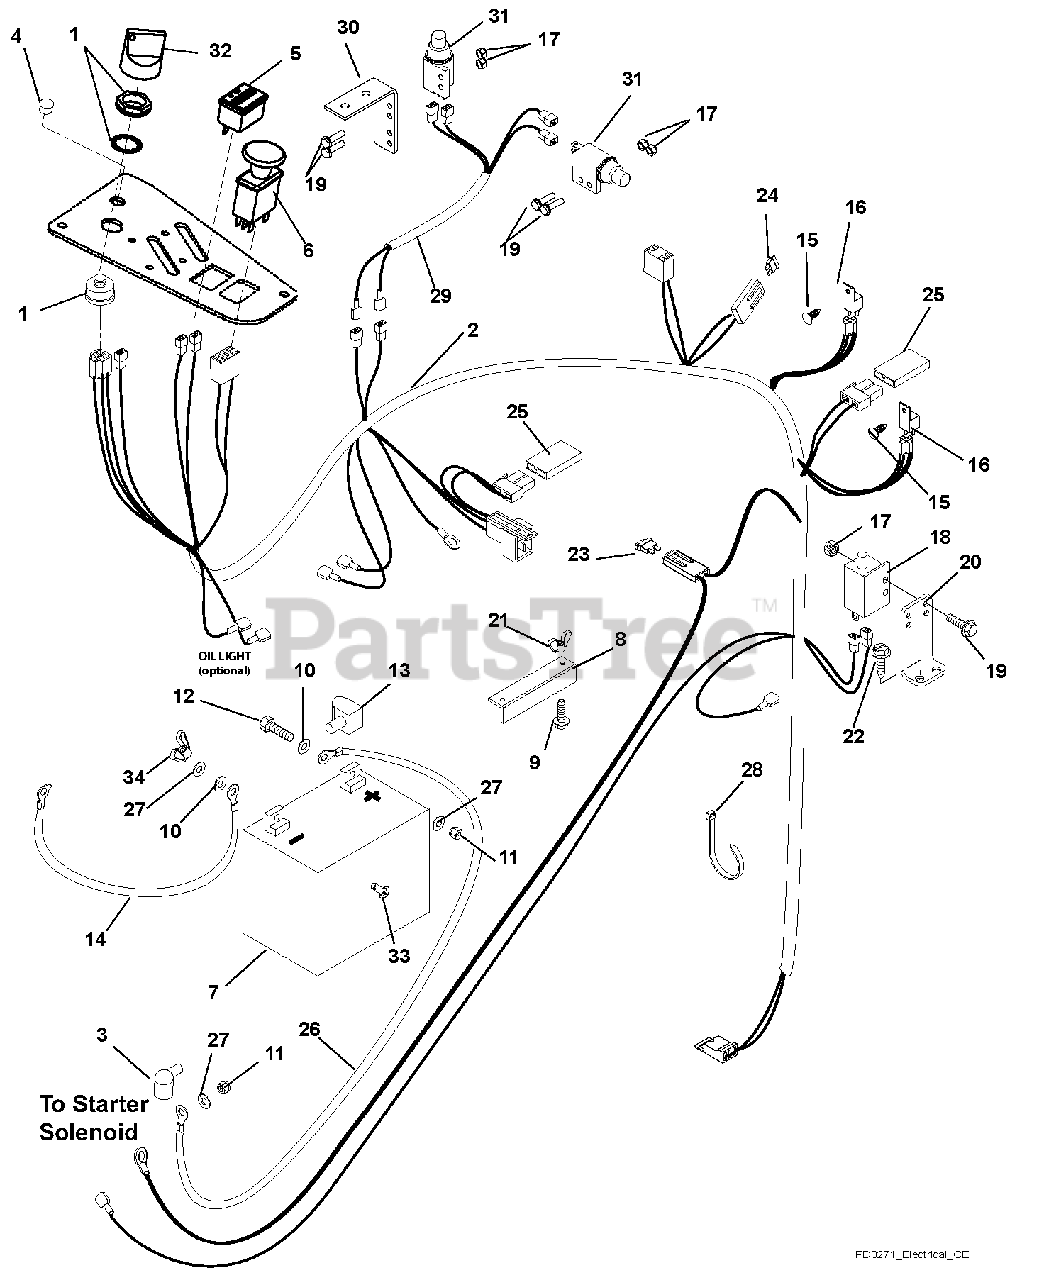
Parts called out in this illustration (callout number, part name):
1	Key Switch Assy (Includes key)
2	Harness, CZ Remote Solenoid
3	Boot, Eyelet Terminal
4	Plug, Hole .50 Diameter
5	Hour Meter – with Maintenance
6	Switch, Clutch with Retainer Ring
8	Hold Down
9	Bolt, Round Head Square Neck .25-20 x 7.50
10	Washer, Flat Steel .281 x .620 x .065
11	Nut, Hex .25-20
12	Bolt, Hex .25-20 x .75 Grade 5
13	Insulator
14	Cable, Negative Battery
15	Rivet, .25 Nylon Panel
16	Relay (Included with Harness)
17	Nut, Locking Nylon 10-24 with Insert
18	Switch, Single Pole
19	Screw, Machine 10-24 x .75 Hex Washer Head
20	Mount, Brake Switch
21	Nut, Locking Wing .25-20
22	Screw, Tapping .25-20 x .50 Hex Washer Head
23	Fuse, 25 Amp (Included with Harness)
24	Fuse, 20 Amp
25	Diode, Connector Shell
26	Cable, Starter
27	Washer, Lock .25 x .062
28	Tie, Cable LG 5.50
29	Harness, CE Foot and Seat Plate Switch
30	Mount, Switch
31	Switch, Single Pole (N.O.) with Cover
32	Key, with Shield
33	Bolt, Round Head Square Neck .25-20 x .75 G5 YZ
34	Nut, Wing .25-20 YZ
